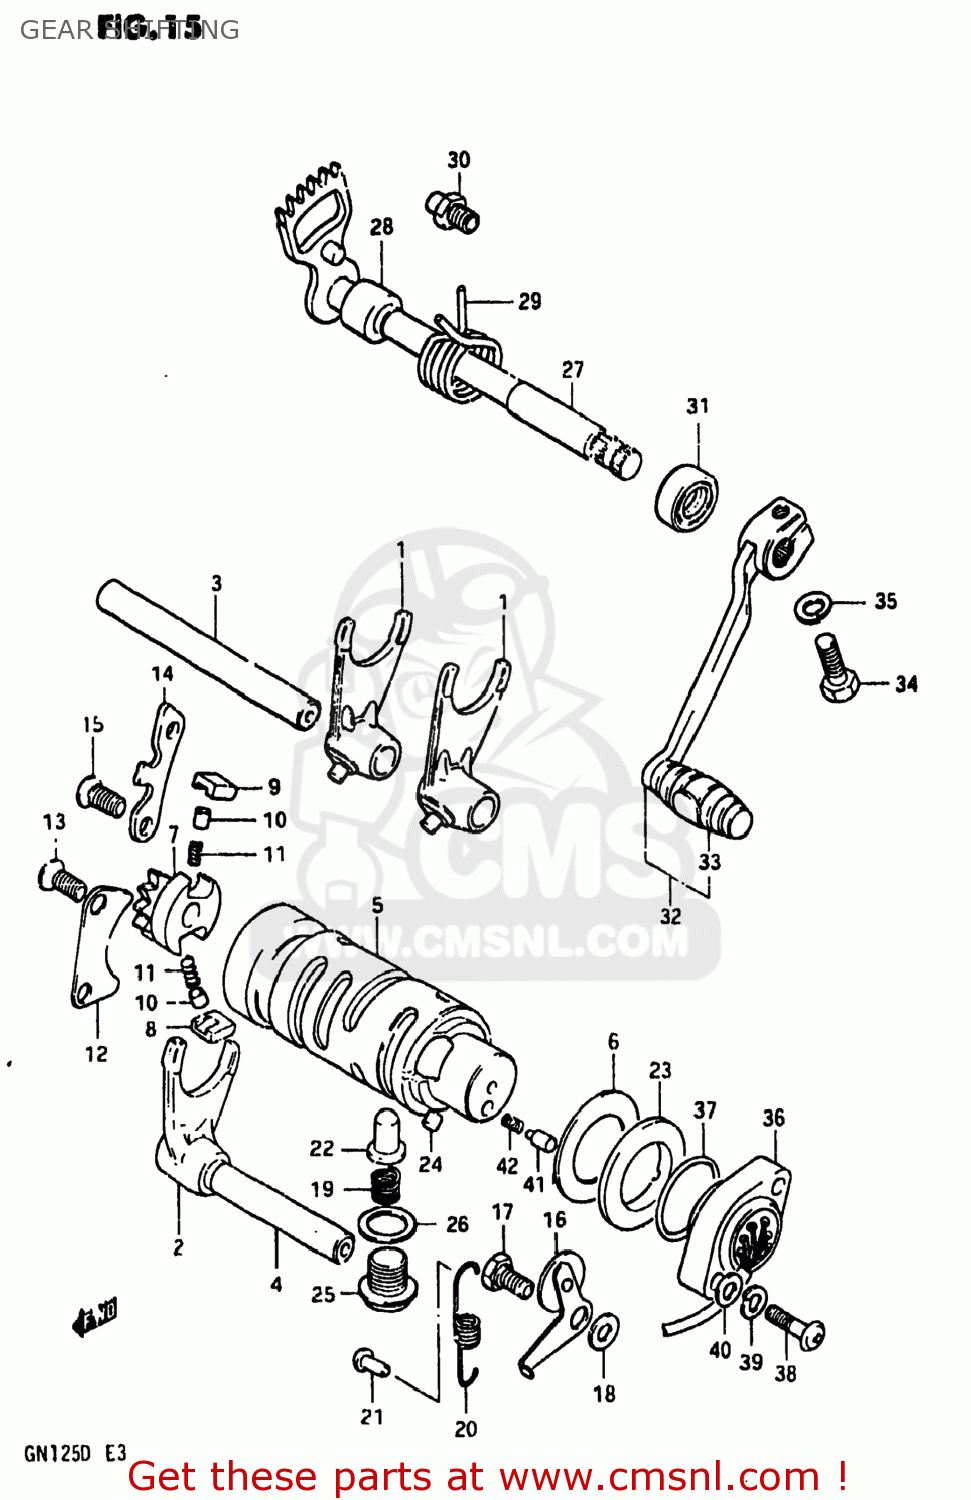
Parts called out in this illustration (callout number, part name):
1	FORK,GEAR SHIFT NO.1
2	FORK,GEAR SHIFT NO.3
3	SHAFT,GEAR SHIFT FORK
4	SHAFT,GEAR SHIFT FORK
5	CAM,GEAR SHIFT
6	WASHER,THRUST
7	RETAINER,GEAR SHIFT CAM
8	PAWL,GEAR SHIFT NO.1
9	PAWL,GEAR SHIFT NO.2
10	PIN(5X8)
11	SPRING
12	LIFTER,GEAR SHIFT PAWL
13	SCREW
14	GUIDE,GEAR SHIFT CAM
15	SCREW
16	STOPPER,GEAR SHIFTING
17	BOLT
18	WASHER
19	SPRING
20	SPRING
21	RIVET
22	STOPPER,GEAR SHIFT CAM NO.2
23	PLATE,GEAR SHIFT CAM STOPPER
24	PIN 4X6
25	PLUG (14X12)
26	GASKET(14X19.2X2) (NAS)
27	SHAFT,GEAR SHIFT
28	SPACER(12X20X15.3)
29	SPRING
30	STOPPER,GEAR SHIFT CAM
31	OIL SEAL
32	LEVER ASSY,GEAR SHIFT
33	RUBBER,GEAR SHIFT PEDAL
34	BOLT
35	LOCK WASHER
36	BASE ASSEMBLY,NEUTRAL SWITCH TERMINAL
37	O-RING (D:2.4 ID:26.2)
38	SCREW 5X20
39	LOCK WASHER
40	WASHER
41	PIN(5X15.5)
42	SPRING
